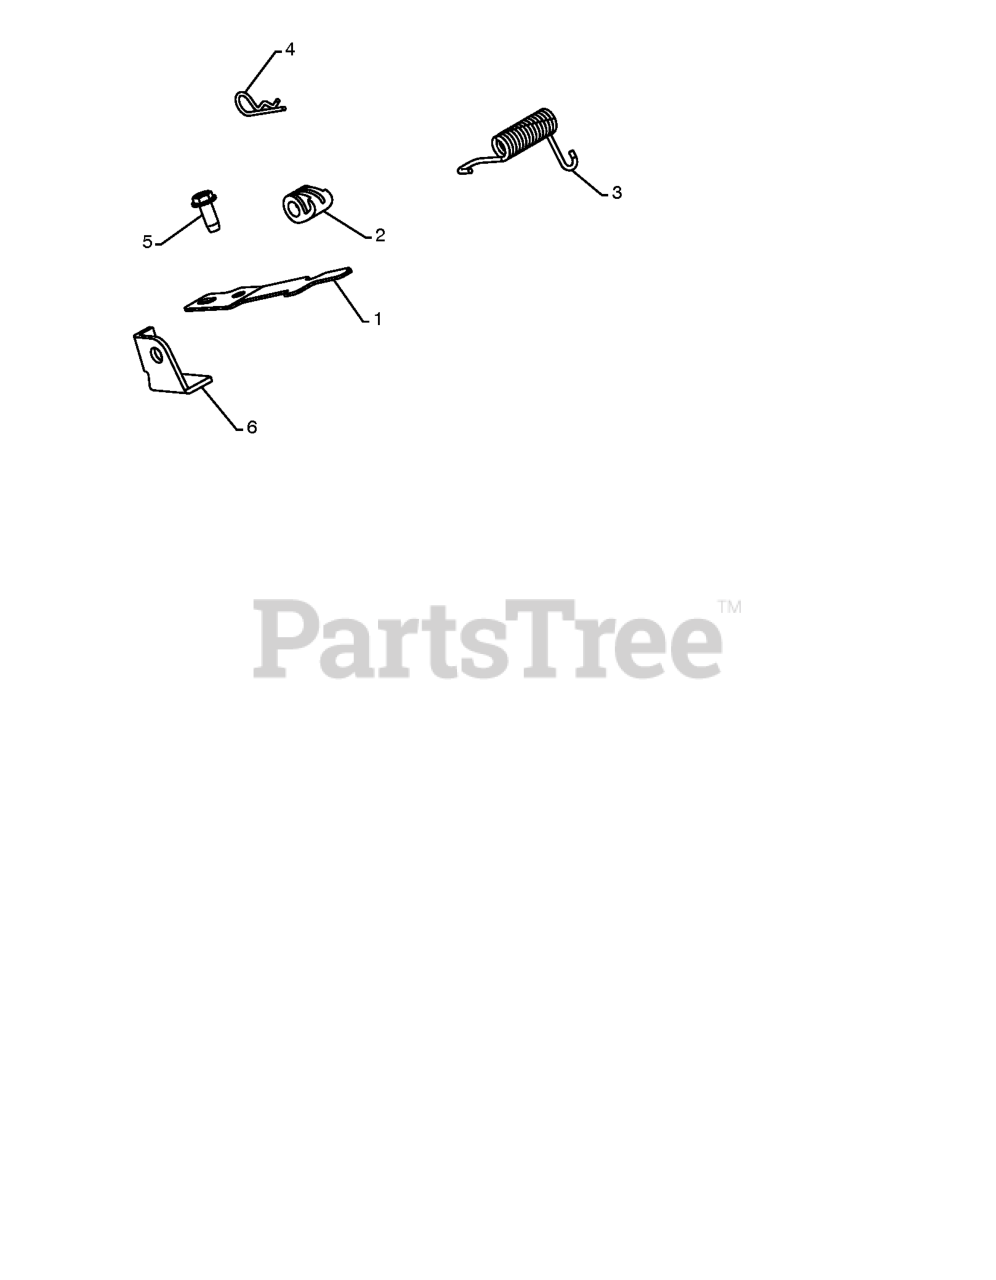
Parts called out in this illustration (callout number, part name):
1	SPRING.INTERLOCK
2	CAM.INTERLOCK.RELEASE
3	RP SPRING, TORSION
4	SPRING RETAINER
5	SCREW 14-20 X 5/8
6	STOP.INTERTLOCK
